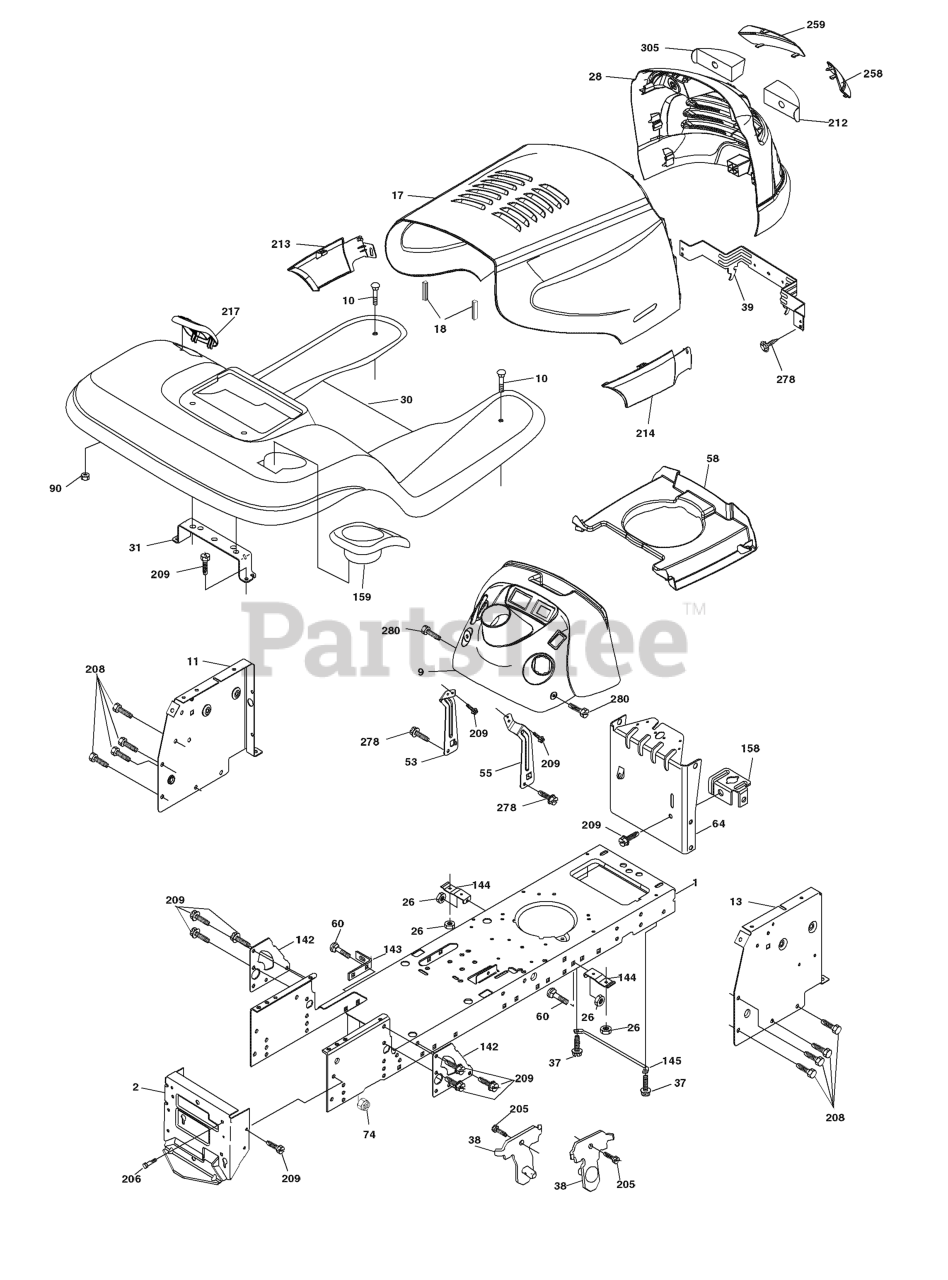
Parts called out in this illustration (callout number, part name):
1	CHASSIS STAMPING
2	DRAWBAR, 12GA
9	DASH.PANEL.GREY
10	BOLT D
11	PANEL.DASH.LH.LTX
13	PANEL DASH RH
17	HOOD
18	BUMPER.HOOD.LARGE.1.75"
26	NUT
28	GRILL/LENS ASSY ( YT MODEL)
30	FENDER
31	BRACKET.SUPPORT.FENDER
37	Screw Thdrol 6/16-18 x 1/2 TYT
38	BRACKET.ASM.PIVOT.MOWER.REAR
39	BRACKET PIVOT
53	BRACKET DASH LH
55	BRACKET DASH RH
58	AIR DUCT P/L/LT
60	Bolt RDHD Sqnk 3/8-16 unc x 3/4
64	DASH LOWER
90	NUT.PUSH.3/16
142	PLATE REINFORCEMENT
143	BRACKET, SWAYBAR CHASSIS
144	BRKT, FOOT REST
145	ROD.PIVOT.HOOD
158	BRACKET PARKING BRAKE
159	CUPHOLDER
205	SCREW LT
206	SHOULDER BOLT 5/16-18TT
208	Screw Thdrl 3/8-16 x 1/2
209	SCREW, 3/8-16X3/4
212	INSERT LENS
213	SKIRT SIDE LH
214	SKIRT SIDE RH
217	CONSOLE FUEL WINDOW
258	LENS ELITE CLEAR RH
259	LENS ELITE CLEAR LH
278	SCREW.#10 X 0.750.BOS
280	SCREW 3/8-16X1
305	INSERT.REFLECTIVE.RH.
305	PLUG BUTTON T
